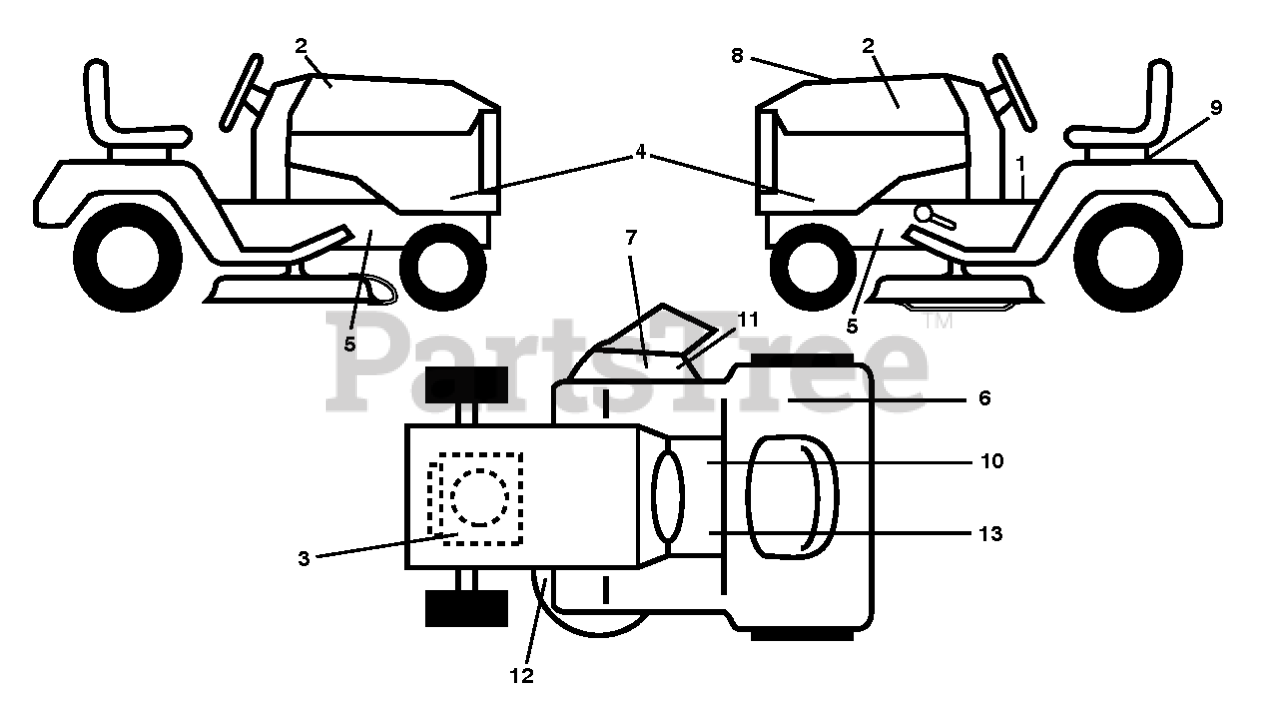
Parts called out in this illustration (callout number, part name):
1	LABEL
2	DECAL.BADGE.170MM.TEXTLOGO.
3	DECAL
4	DECAL SIDE PANEL
6	Decal, Fender 100 DB/CE
7	DECAL.INTERNATIONL.CUTFINGER
9	DECAL BTRY SYMBOLS
10	DECAL PARK BRAKE
11	DECAL, DEFLECT WARNING
12	DECAL.V-BELT.SCHEMATIC.36/38/9
13	DECAL
